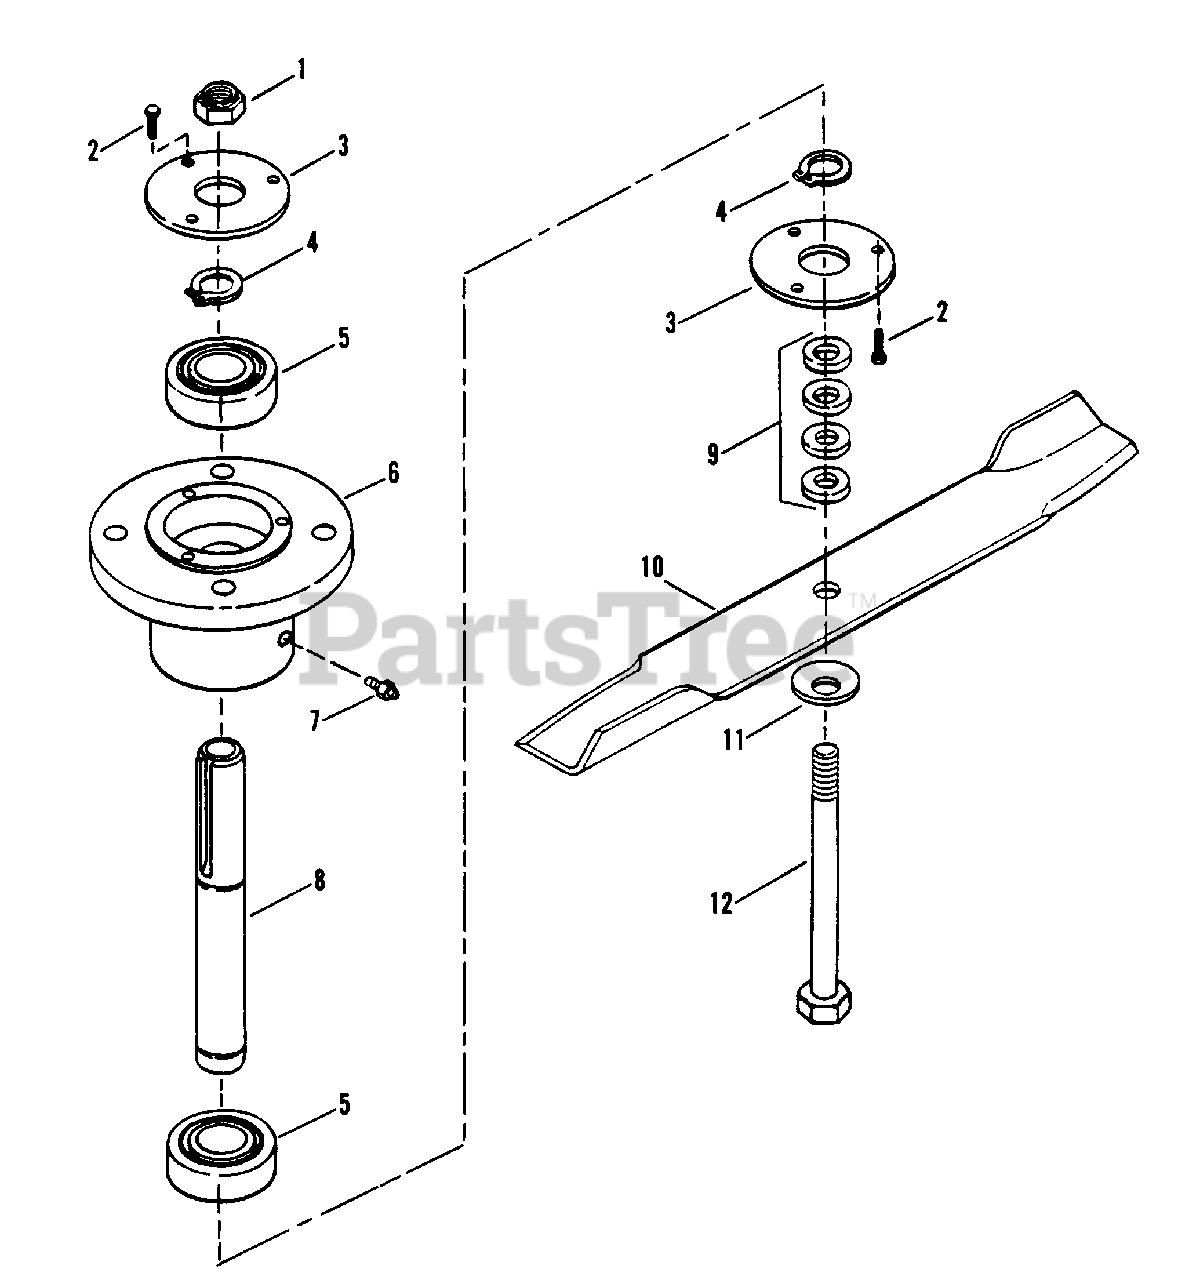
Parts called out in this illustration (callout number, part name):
1	NUT, 5/8-18 Hex
2	SCREW, #10-24 x 1/2" Self-Tapping
3	CAP, Cutter Housing
4	RING, Retaining
5	BEARING, Single Seal
6	HOUSING, Cutter
7	ZERK, 1/8 NPT
8	SPINDLE, Cutter
9	SPACER, Blade
10	BLADE, 18"
11	WASHER, Beveled
12	BOLT, 5/8-18 x 7 1/2" Hex Head Cap
